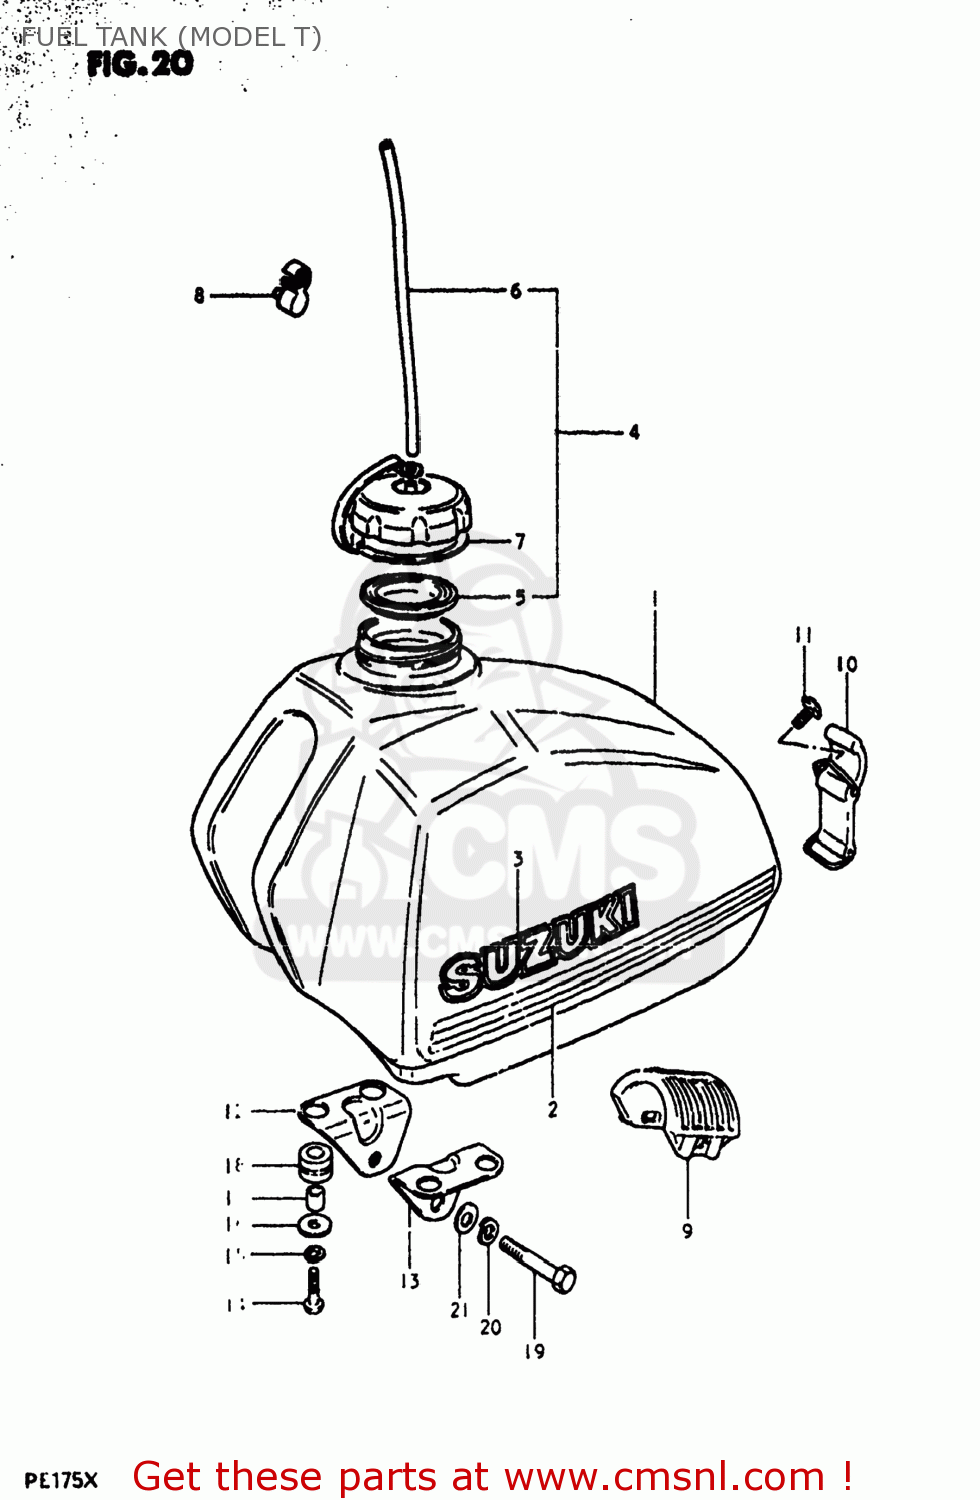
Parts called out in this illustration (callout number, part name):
1	TANK ASSEMBLY,FUEL
2	TAPE SET,FUEL TANK
3	EMBLEM
4	CAP,FUEL TANK
5	GASKET,FUEL TANK CAP (NAS)
6	HOSE
7	BAND,FUEL TANK CAP
8	CLAMP,BREATHER HOSE
9	CUSHION,FUEL TANK
10	BAND
11	SCREW(6X18)
12	BRACKET,FUEL TANK,LOWER
13	BRACKET,FUEL TANK
14	SCREW
15	LOCK WASHER
16	WASHER (6.5X24X1.6)
17	SPACER(6.8X12X11)
18	CUSHION
19	HEXAGON BOLT 8X80
20	LOCK WASHER
21	WASHER
